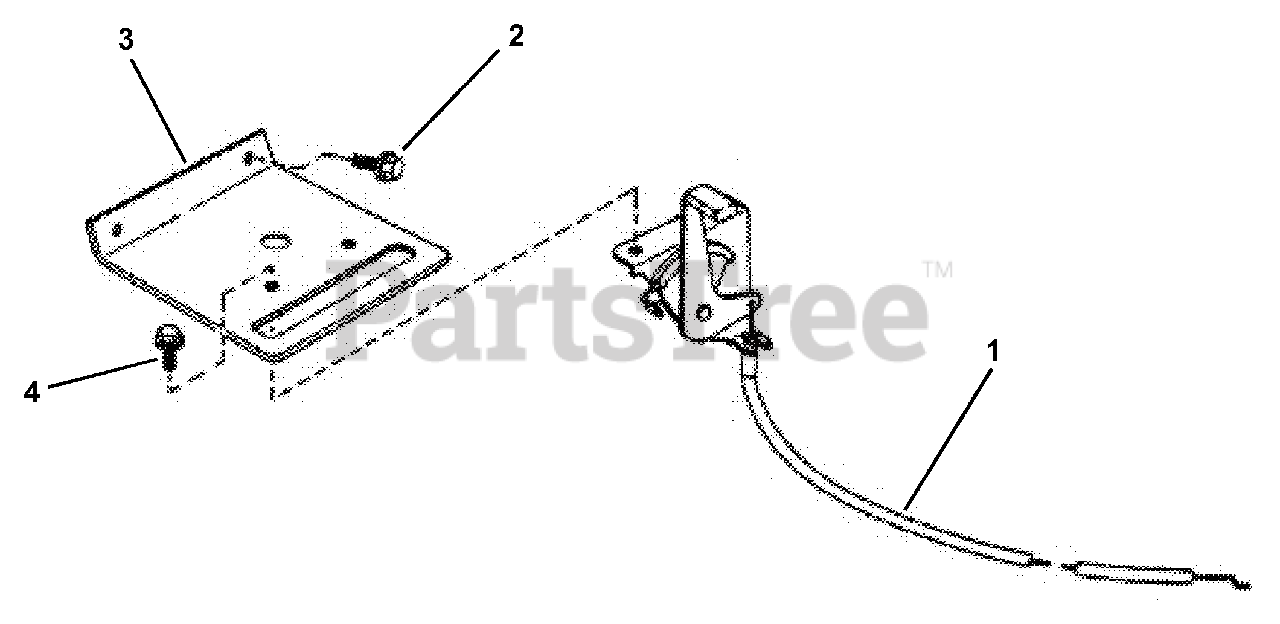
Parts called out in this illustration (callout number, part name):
1	CONTROL, Throttle (23.6" long) (Briggs Engines)
2	SCREW, 1/4-20 x 1/2" Hex Washer Self-Tap
3	PLATE, Throttle Control
4	SCREW, #10-24 x 1/2" Hex Washer Self-Tap (Torx)
